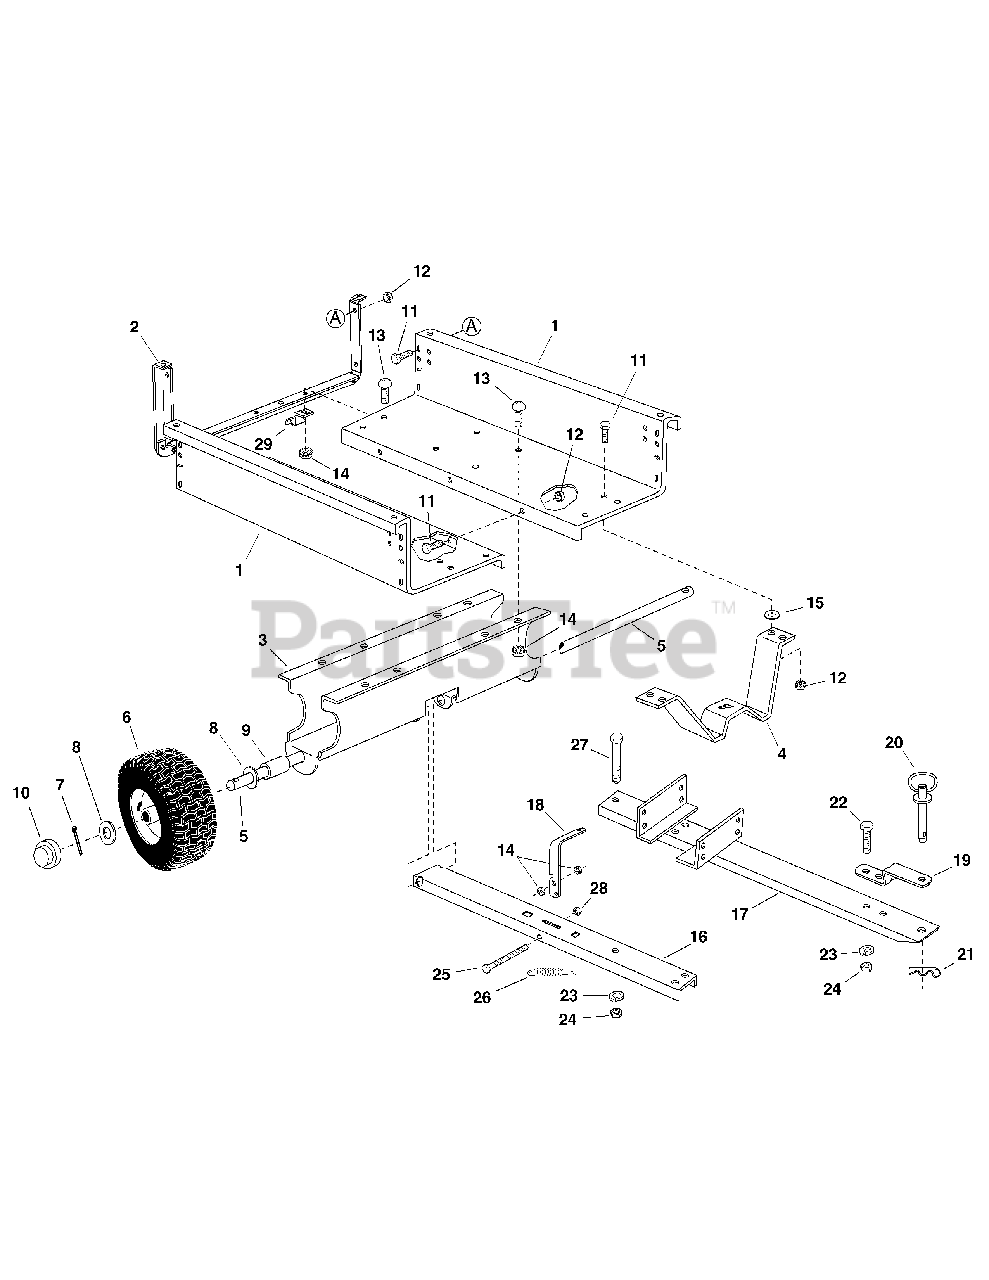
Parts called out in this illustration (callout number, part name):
5	Axle, Wheel 1" Dia.
6	Wheel w/Tire, 15 x 6.00
7	Cotter Pin, 1/8" Dia. x 1-1/2"
8	Washer, Flat 1"
9	Spacer Tube, 1-1/4" x 2" Lg.
10	Hub Cap
11	Hex Bolt, 1/4-20 x 5/8"
12	Hex Nut, 1/4-20 (SEMS)
13	Truss Hd. Bolt, 5/16-18 x 3/4"
14	Hex Nut, 5/16-18 (SEMS)
15	Washer, Flat 1/4"
16	Tongue Weldment Ass'y. (Rear)
17	Tongue Weldment Ass'y. (Front)
18	Latch Lock Lever
19	Hitch Bracket
20	Hitch Pin
21	Pin, Hair Cotter 1/8"
22	Hex Bolt, 3/8-16 x 1-1/4"
23	Lockwasher, 3/8"
24	Hex Lock Nut, 3/8-16
25	Hex Bolt, 5/16-18 x 3-3/4"
26	Spring, Extension
27	Hex Bolt, 3/8-16 x 3"
28	Hex Lock Nut, 5/16-18
29	Door Support
